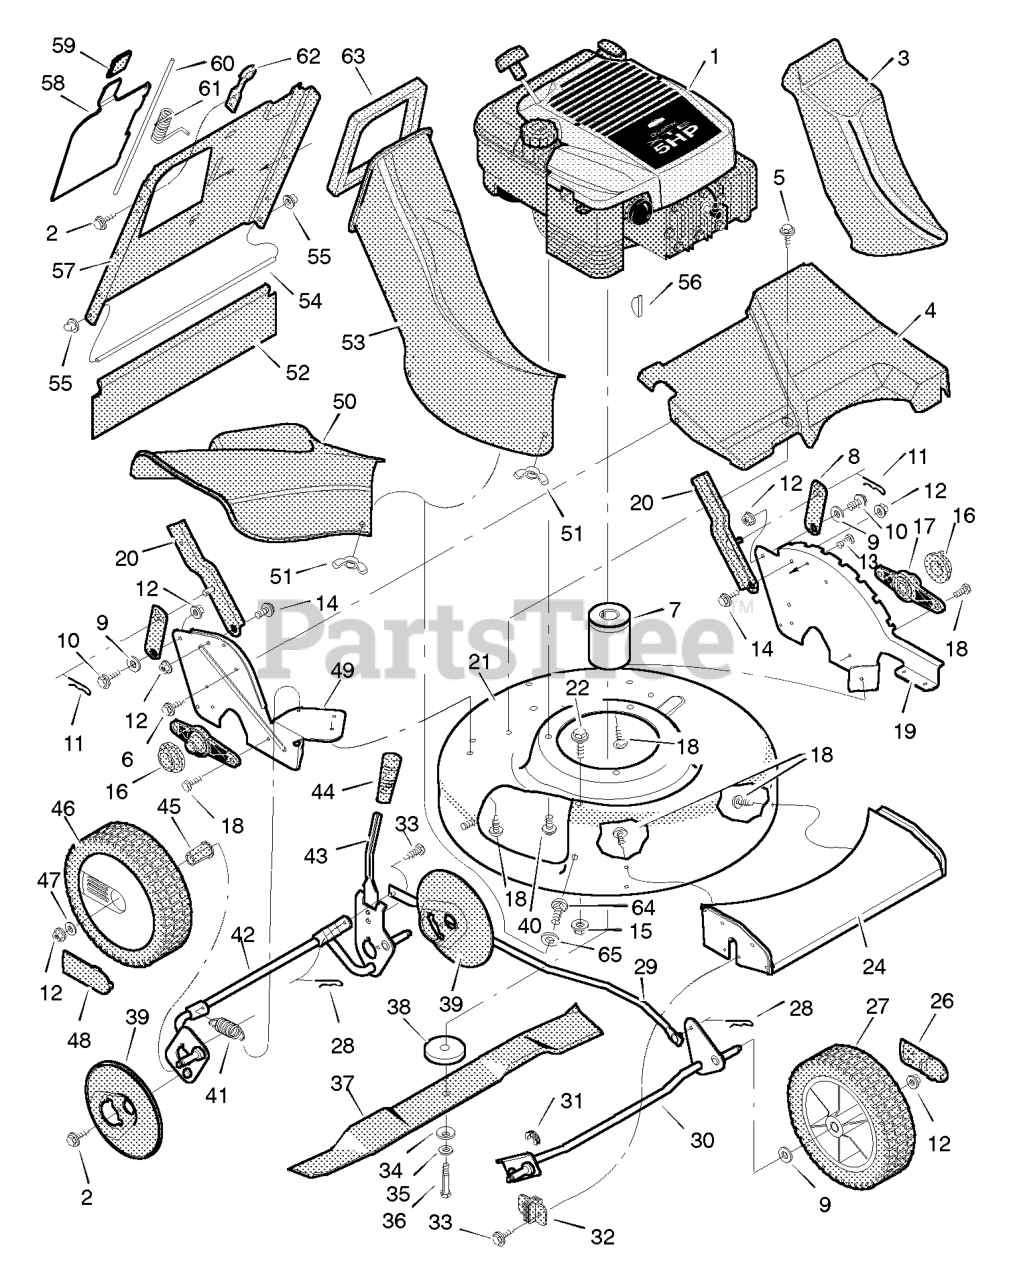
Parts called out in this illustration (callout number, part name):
1	Engine *
2	Screw
3	Plug, Mulcher
4	Cover, Rear
7	Adapter, Blade
8	Strap, Adjuster
9	Washer, Spring
10	Bolt, Shoulder
11	Pin, Hair
12	Locknut, Flange
13	Nut, Hex
14	Bolt, Shoulder
16	Bearing, Lifter
17	Support, Axle
19	Index, Height Adjuster
20	Bracket, Handle
21	Housing (Red)
22	Bolt, Shoulder
24	Panel, Front
26	Cap - Ball Bearing (Red)
27	Wheel, Front (Gray)
28	Pin, Hair
29	Link, Lifter
30	Crossbar Assembly, Front
31	Bushing
32	Clip, Front Axle
34	Washer, Belleville
36	Bolt, Hex
38	Spacer, Adapter
39	Cover, Dust
40	Bolt, Engine
41	Spring, Extension
42	Crossbar Assembly, Rear
43	Lever, Height Adjuster
44	Grip, Height Adjuster
45	Bushing
46	Wheel, Rear (Gray)
47	Washer
48	Hub Cap (Red)
49	Support, Wheel
50	Deflector, Chute
51	Nut, Wing
52	Guard, Rear
53	Deflector, Rear
55	Cap, Push On
56	Key, Woodruff #6
57	Plate, Bagger
58	Door, Rear
59	Grip, Door
60	Rod, Door
61	Spring, Torsion
62	Guide, Rope
64	Bolt, Carriage
65	Retainer
